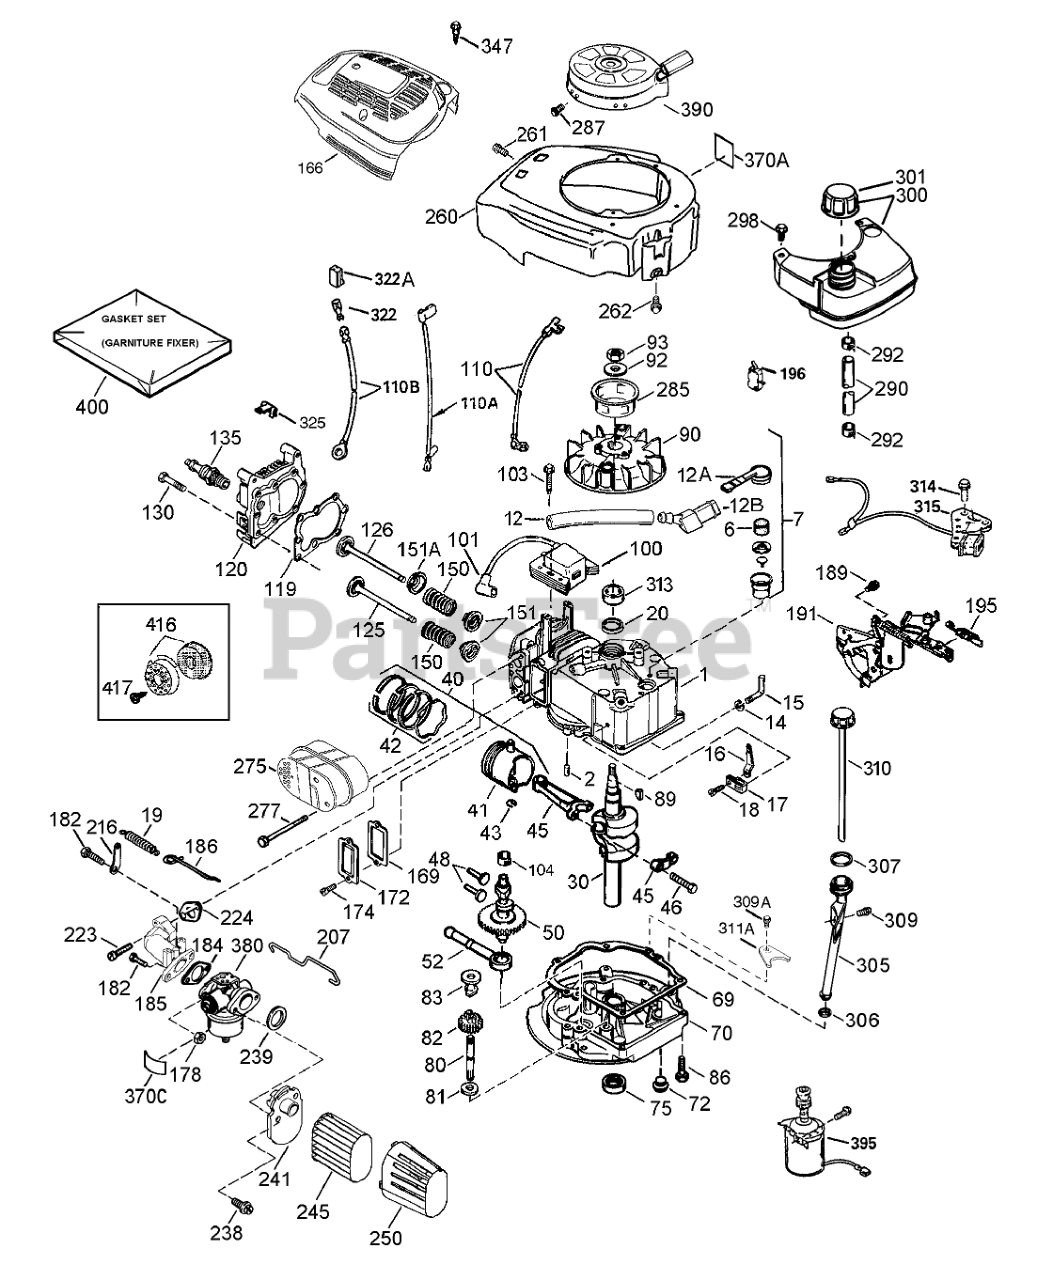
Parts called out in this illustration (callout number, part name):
1	Cylinder (Incl. 2,20 & 150)
2	Pin-Dowel
6	Element-Breather
7	Breather Body ASM (Incl. 6 & 12A)
12	Tube-Breather
12A	Breather Cover and Tube ASM
12B	Elbow-Tube, Breather
14	Washer-Flat
15	Governor Rod (Incl. 14)
16	Lever-Governor
17	Clamp-Lever, Governor
18	Screw (T-15, 8-32 x 19/64)
19	Spring-Extension
20	Seal-Oil
30	Crankshaft
40	Piston, Pin and Ring Set (Std.)
41	Piston & Pin ASM(Std.)(Incl. 43)
42	Ring Set (STD)
43	Ring-Retaining, Piston Pin
45	Connecting Rod ASM(Incl. 46)
46	Bolt-Rod, Connecting
48	Lifter-Valve
50	Camshaft ASM (Exhaust M C R)
52	Oil Pump ASM
69	Gasket-Flange, Mounting
70	Mounting Flange(Incl. 72 thru 83)
72	Plug-Drain, Oil
75	Seal-Oil
80	Shaft-Governor
81	Washer-Flat
82	Governor Gear ASM(Incl. 81)
83	Spool-Governor
86	Screw (1/4-20 x 1-1/4)
89	Key-Flywheel
90	Flywheel
92	Washer-Belleville
93	Nut-Flywheel
100	Ignition-State, Solid
101	Cover-Spark Plug
103	Screw (T-15, 10-24 x 15/16)
104	Bushing-Cam
110	Wire-Ground
110A	Wire ASM
110B	Wire ASM
119	Gasket-Cylinder Head
120	Head-Cylinder
125	Exhaust Valve (1/32" OS)(Incl. 151)
125	Exhaust Valve(Std.)(Incl. 151)
126	Intake Valve (Std.)(Incl. 151)
130	Screw (5/16-18x1-1/2)
135	Spark Plug-Resistor (R J19 L M)
150	Spring-Valve
151	Cap-Valve, Spring
151A	Seal-Valve, Intake
166	Shroud-Engine
169	Gasket-Cover, Valve
172	Cover-Valve
174	Screw (10-24 x 9/16)
178	Nut and Lock Washer (1/4-28)
182	Screw (1/4-28 x 7/8)
184	Gasket
185	Pipe-Intake
186	Link-Governor
189	Screw (1/4-20 x 1/2)
191	S.E. Brake Bracket(Incl. 195)
195	Terminal
196	Switch-Restart, Power
207	Link-Throttle
216	Lever-Adjusting, R P M
223	Screw (1/4-20 x 1)
224	Gasket-Pipe, Intake
238	Screw (10-32 x 49/64)
239	Gasket-Cleaner, Air
241	Collar-Cleaner, Air
245	Filter-Cleaner, Air (Paper)
250	Cover-Cleaner, Air
260	Blower Housing
261	Screw (10-24 x 9/16)
262	Screw (1/4-20 x 1/2)
275	Muffler
277	Screw (1/4-20 x 2-9/32)
285	Cup-Starter
287	Screw (8-32 x 21/64)
290	Fuel Line
292	Clamp-Line, Fuel
298	Screw (10-32 x 35/64)
300	Fuel Tank(Incl. 292 & 301)
301	Cap-Fuel
305	Tube-Fill, Oil
306	O-Ring
307	O-Ring
309	Screw (10-32 x 1/2)
309A	Screw (10-24 x 3/4)
310	Dipstick
311A	Bracket-Holddown
313	Spacer
314	Screw (8-32x27/64)
315	Coil
322	Body-Connector
322A	Terminal
325	Clip-Actuator, Brake Switch
347	Screw (10-32 x 27/32)
370A	Decal-Lubrication
370C	Decal-Primer
380	Carburetor (Incl. 184)
390	Rewind Starter ASM
395	Electric Starter
400	Gasket Set
416	Spark Arrestor Kit (Incl. 417) (Optional)
417	Screw (8-32 x 3/8)
